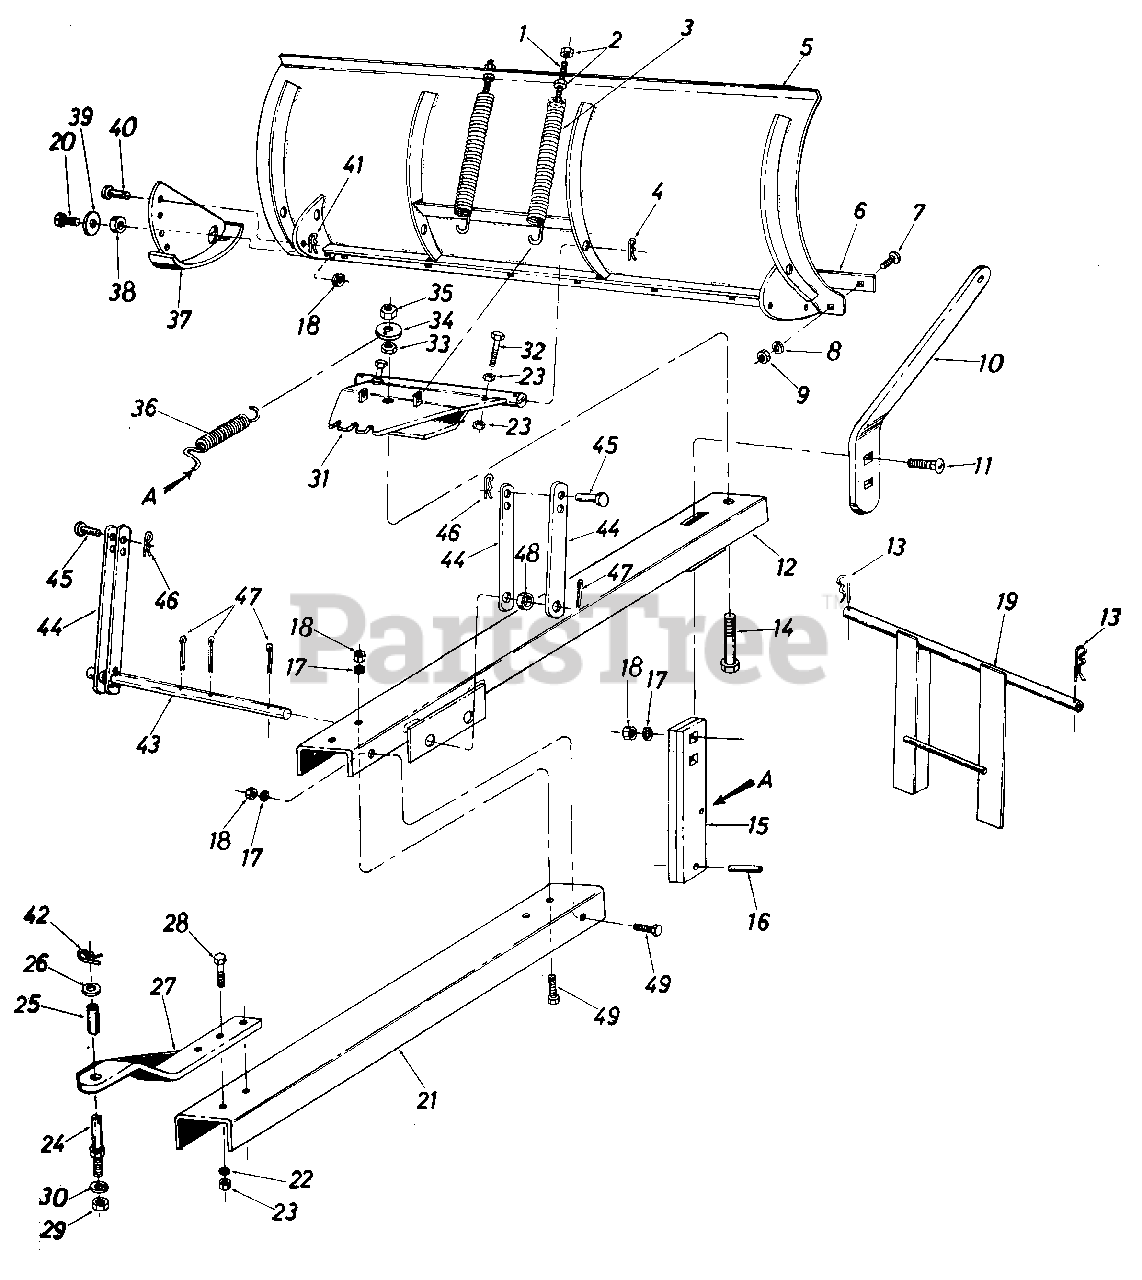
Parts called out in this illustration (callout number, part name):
1	Hex Scr. 3/8-16 x 4.50" Lg.
2	Hex Nut 3/8-16 Thd.
3	Blade Adjustment Spring
4	Hair Pin Cotter, 5/32
5	54" Blade Ass'y.
6	Wear Plate
7	Carriage Bolt 5/16-18 x .75" Lg.
8	L.-Wash. 5/16" Scr.
9	Hex Nut 5/16-18 Thd.
10	Lock Extension Bar
11	Carriage Bolt 3/8-16 x 1.25" Lg.
12	Front Push Bar Ass'y.
13	Hair Pin Cotter, 5/32
14	Hex Scr. 3/4-10 x 3.50" Lg.
15	Angle - Lock Bar
16	Spring Pin Spirol .25" Dia. x 1.00" Lg.
17	L.-Wash. 3/8" Scr.
18	Hex L.-Nut 3/8-16 Thd.
19	Guide Bracket Ass'y.
20	Hex Scr. 3/8-16 x .75" Lg.
21	Rear Push Bar Channel
22	L.-Wash. 1/2" Scr.
23	Hex Nut 1/2-13 Thd.
24	Link Clevis Pin
25	Spacer 1" O.D. x 21/32" I.D. x .75" Lg.
26	Fl-Wash. 21/32 I.D. x .090 O.D.
29	Hex Jam L.-Nut 5/8-18 Thd.
30	L.-Wash. 5/8" Scr.
31	Pivot Plate Ass'y.
32	Hex Scr. 1/2-13 x 2.00" Lg.
33	Hex Jam Nut 3/4-10 Thd.
34	Fl.-Wash. 3/8" (Special)
35	Hex Lock Nut 3/4-10 Thd.
36	Angle Lock Spring
37	Skid Assembly
38	Bushing, Pivot Skid
39	Fl.-Wash. .385" I.D. x 1.00" O.D.
40	Clevis Pin 5/16" Dia. x 3/4" Lg.
41	Hair Pin Cotter 3/32"
42	Hair Pin Cotter, 5/32
43	Lift Shaft
44	Lift Link
45	Clevis Pin 1/2" Dia. x 1.00" Lg.
46	Hair Pin Cotter, 3/32"
47	Cotter Pin 1/8" Dia. x 1.50" Lg.
48	Spacer, Lift Link
49	Hex Scr. 3/8-16 x 1.00" Lg.
